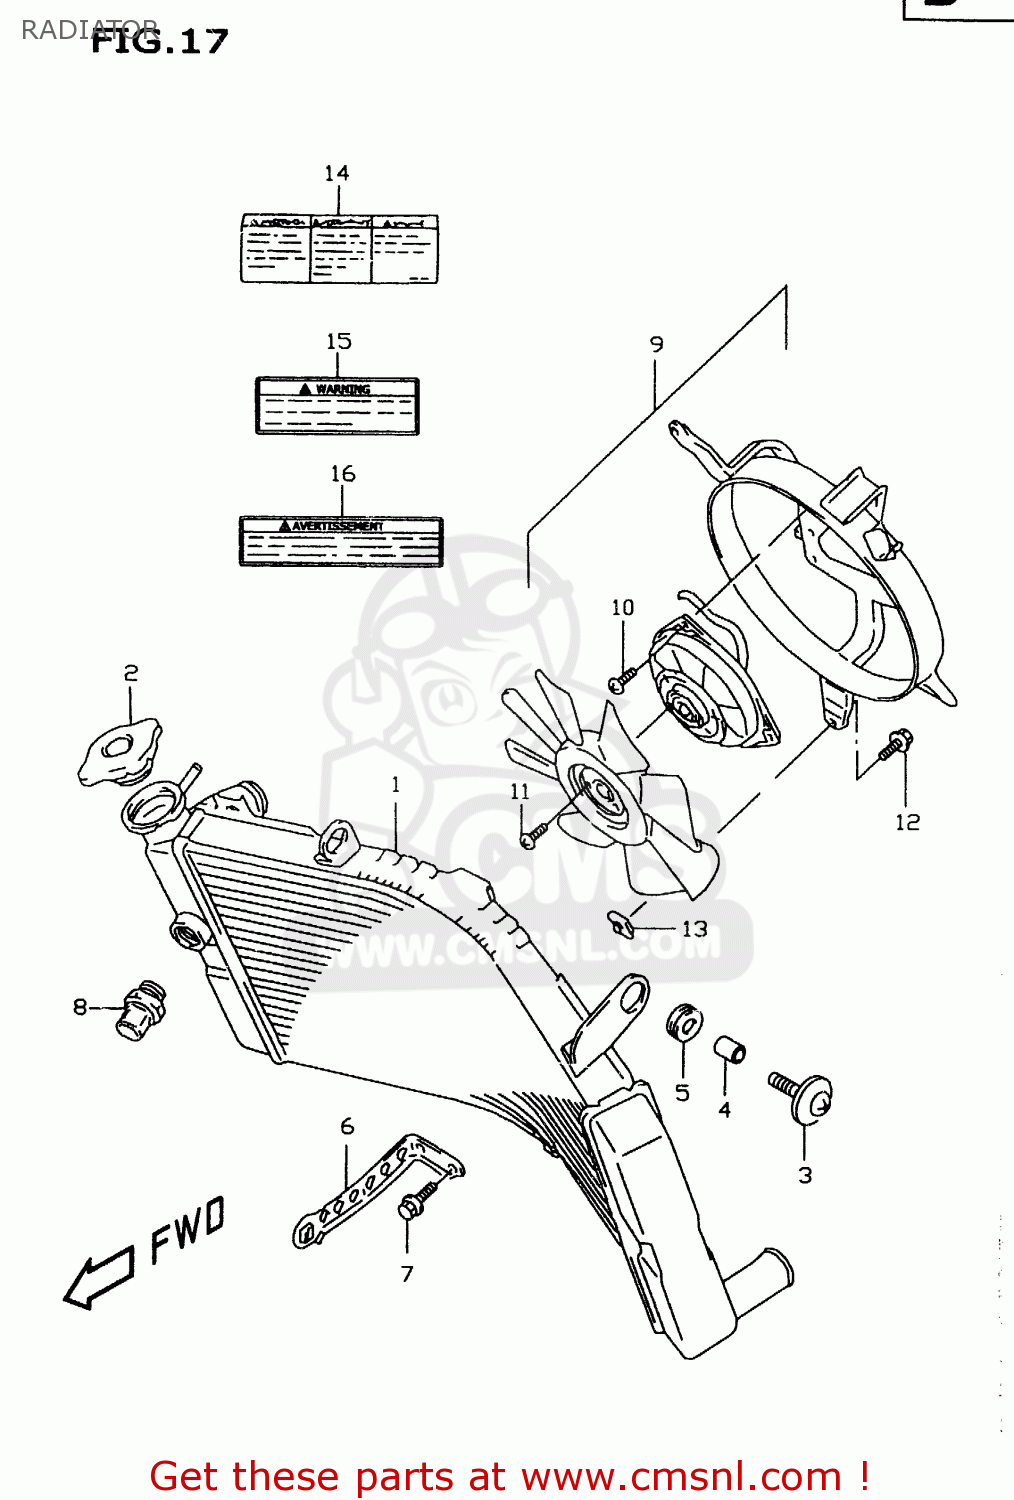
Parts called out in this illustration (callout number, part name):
1	RADIATOR ASSY,WATER
2	CAP,RADIATOR
3	BOLT 6X20
4	SPACER(6.5X10X12)
5	CUSHION
6	BRACKET,RADIATOR LWR
7	BOLT
8	SWITCH,RADIATOR FAN
9	FAN ASSEMBLY,RADIATOR
10	SCREW
11	SCREW 4X6
12	BOLT
13	NUT,RADIATOR COVER
14	LABEL, COOLING FAN
15	LABEL (COOLING FAN)
16	LABEL,COOLING FAN
